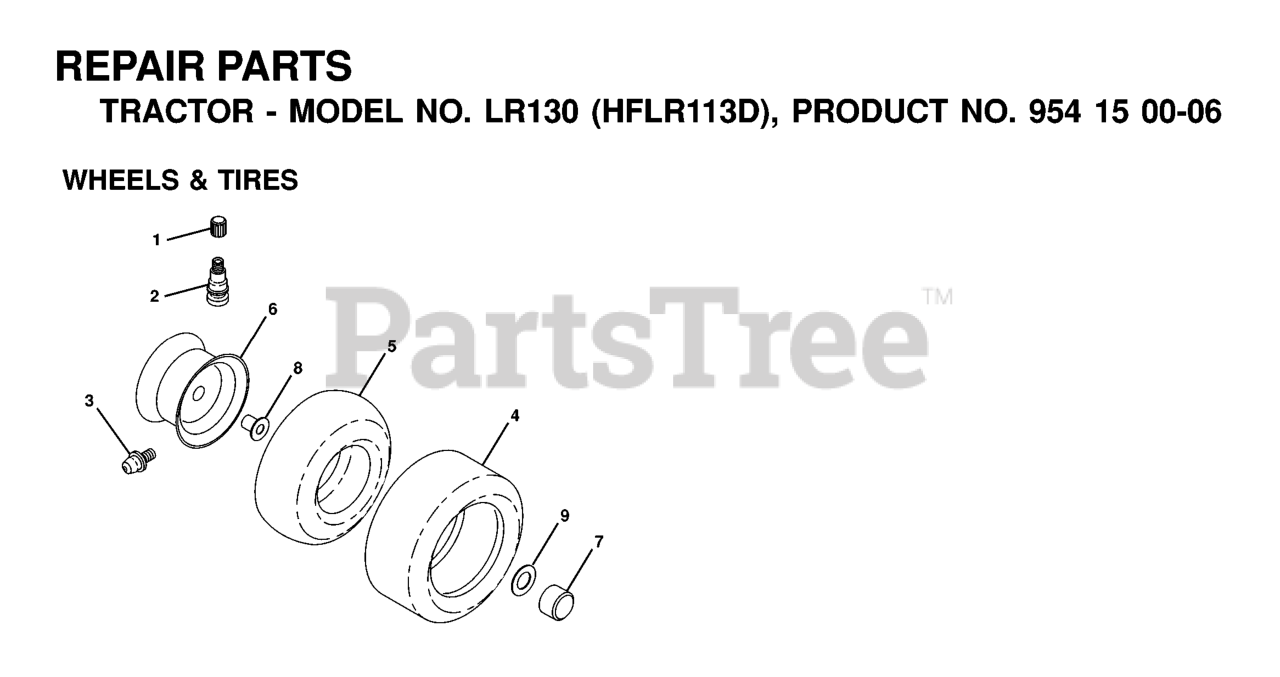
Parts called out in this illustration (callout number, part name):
2	VALVE STEM LT
3	FITTING LT
4	TIRE FRONT 15X6-6
5	TUBE.5.3/4.5/6
5	TUBE.16X6.5/7.5-8
6	RIM REAR 8"
6	RIM
7	CAP.HUB.FRONT.LT.BLACK
8	BEARING T
9	WASHER
